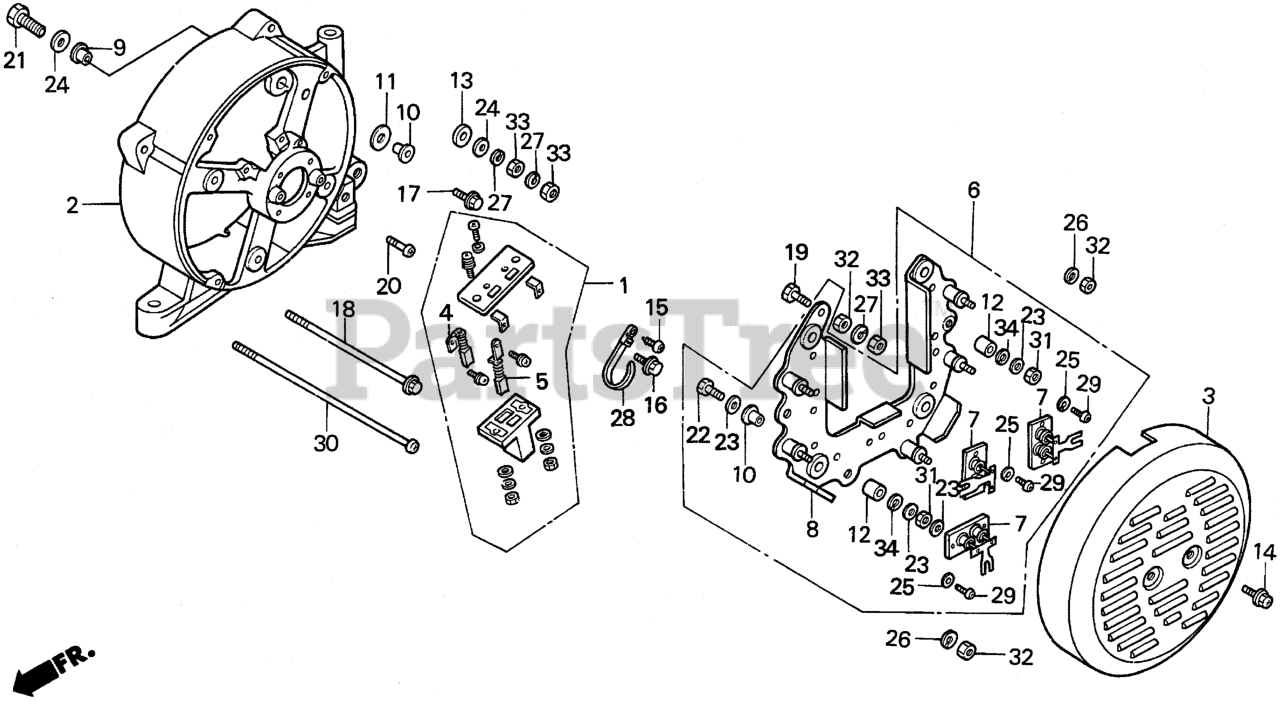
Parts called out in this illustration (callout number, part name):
1	HOLDER ASSY., BRUSH
2	HOUSING, RR.
3	COVER, GENERATOR END
6	DIODE ASSY.
8	PLATE, HEAT SINK
9	BUSH, INSULATING (6MM)
10	BUSH, INSULATING (5MM)
11	WASHER, INSULATING
12	INSULATOR (5MM)
13	WASHER, INSULATING
14	SCREW, TAPPING (5X8)
15	SCREW, TAPPING (4X10)
16	SCREW, TAPPING (5X14)
17	SCREW, TAPPING (5X16)
18	BOLT, FLANGE (6X135)
19	BOLT, HEX. (6X14)
19	BOLT, HEX. (6X16)
20	SCREW, PAN (5X12) (GROUND CABLE)
21	BOLT, HEX. (6X30)
22	BOLT, HEX. (5X35) (NOT AVAILABLE)
22	BOLT, HEX. (5X35)
23	WASHER, PLAIN (5MM) (NOT AVAILABLE)
23	WASHER, PLAIN (5MM)
24	WASHER, PLAIN (6MM)
25	WASHER, SPRING (4MM)
26	WASHER, SPRING (5MM)
27	WASHER, SPRING (6MM)
28	TIE, CABLE
29	SCREW, PAN (4X8)
30	SCREW, PAN (5X175)
31	NUT, HEX. (5MM)
32	NUT, HEX. (5MM)
33	NUT, HEX. (6MM)
34	WASHER, SPRING (5MM)
